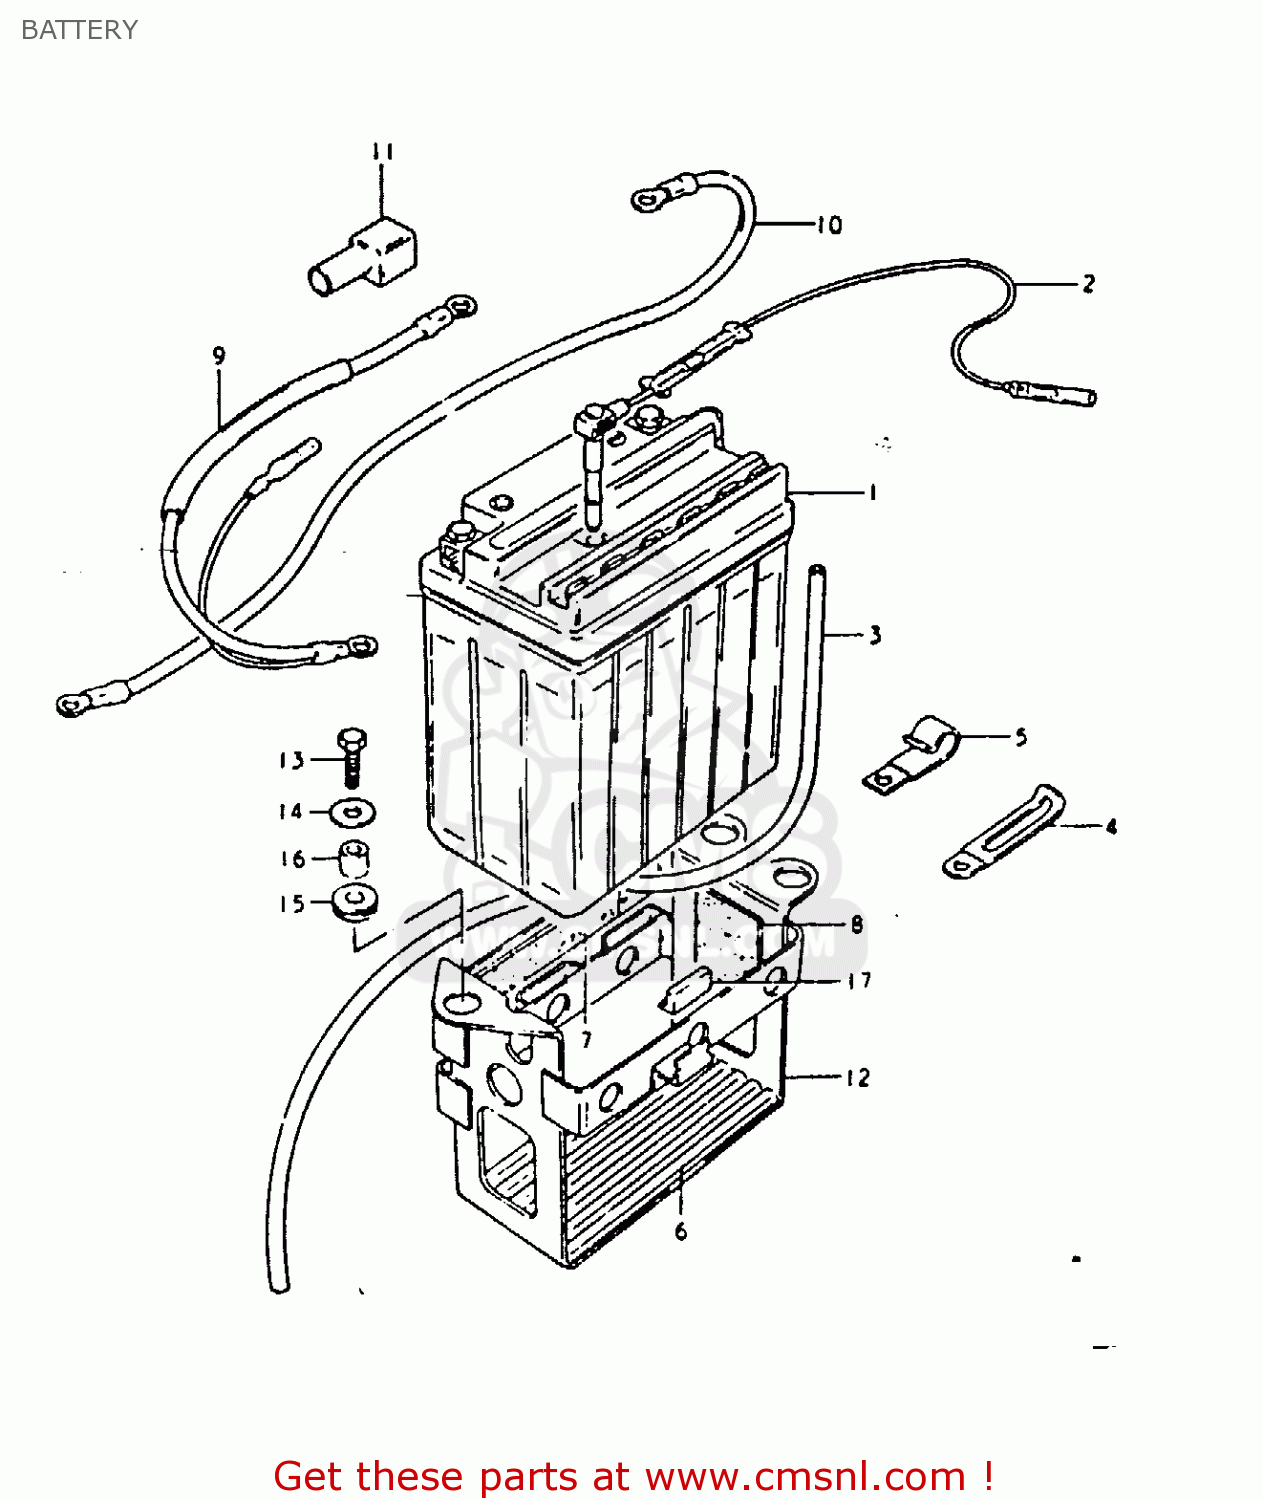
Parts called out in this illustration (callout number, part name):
1	BATTERY ASSEMBLY (12V)
2	SENSOR,BATTERY LEVEL
3	HOSE,BATTERY EXHAUST
4	CLAMP L:35
5	CLAMP
6	PROTECTOR,BATTERY
7	PROTECTOR(20X90)X4
8	PROTECTOR,BATTERY
9	WIRE,BATTERY PLUS
10	LEAD WIRE,BATTERY(-)
11	CAP,TERMINAL
12	HOLDER,BATTERY
13	BOLT, UPPER
14	WASHER
15	CUSHION
16	SPACER(6.1X9X7.5)
17	CUSHION,FRAME COVER
